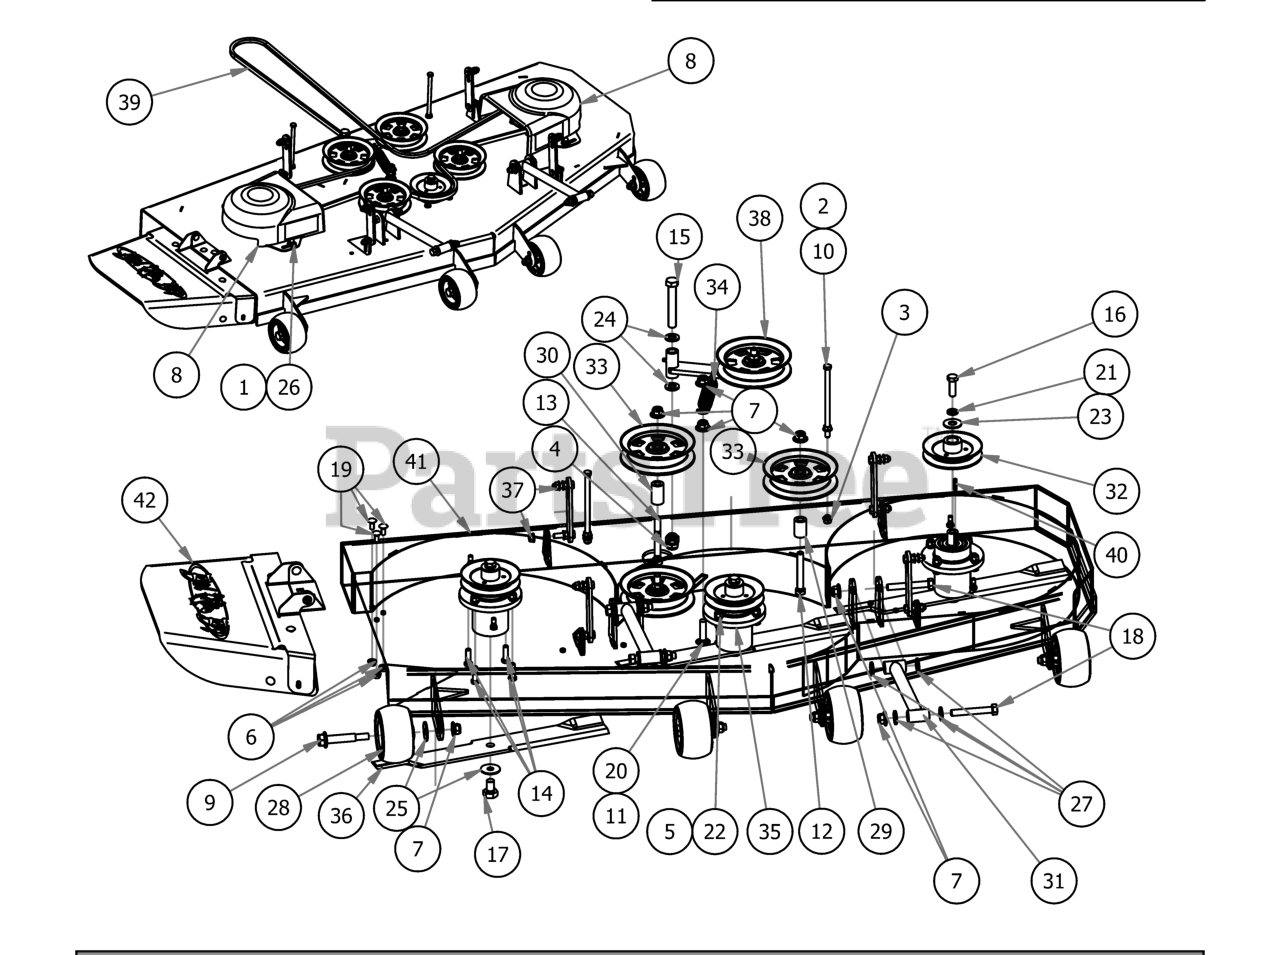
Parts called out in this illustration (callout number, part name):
1	Acorn nut-pulley Cover
2	3/8" Flange Nut
3	3/8" Nylock Flange Nut
4	5/8-11 Nylon Insert Jam Half Nut
5	3/8" Hex Nut
6	5/16-18 NYLON INSERT FLANGE LOCKNUT ZINC
7	1/2-13 NYLON INSERT FLANGE LOCKNUT ZINC
8	Pulley Cover
9	Deck Wheel Bolt
10	3/8-16 X 6.5 HEX CAP SCREW (GR.5) ZINC
11	1/2 x 2" Carriage Bolt
12	1/2 x 3 1/2 Flange Bolt Grade 8
13	1/2" x 4" Bolt (Grade 8)
14	3/8" x 1 1/4" Hex Bolt
15	5/8" x 4" Hex Bolt
16	1/2"-20 x 1 1/2 - Grade 5 Fine Thread Bolt
17	5/8" x 1 1/2" Grade 8 Hex Bolt (Fine)
18	1/2-13 x 3 1/2 GR 5 Hex Bolt
19	5/16-18 x 3/4 Carriage Bolt
20	.517 Square Hole Round Washer
21	1/2" Lock Washer
22	3/8" Lock Washer
23	5/8'' Flat Washer
24	.630 ID Plastic Washer
25	1/2" Belleville Washer
26	.360 ID Plastic Washer-Black
27	.505 Nylon Spacer
28	Deck Wheel
29	.502 ID X .750 OD X 1.500 Long Spacer
30	1 3/4" Pulley Spacer
31	MZ/ZT Deck Locator
32	60" Avenger Deck Pulley
33	5-3/4 Idler Pulley
34	Deck Idler Spring
35	Spindle Assembly-MZ
36	60 Inch Fusion Blade
37	Deck Hanger Assembly
38	2017 54"/48" Deck Idler Assembly
40	3/16 X 1 SQ MACHINERY KEY 1018 STL ZINC
41	60" MZ Deck Welment-Painted
42	MZ Discharge Chute Assembly
